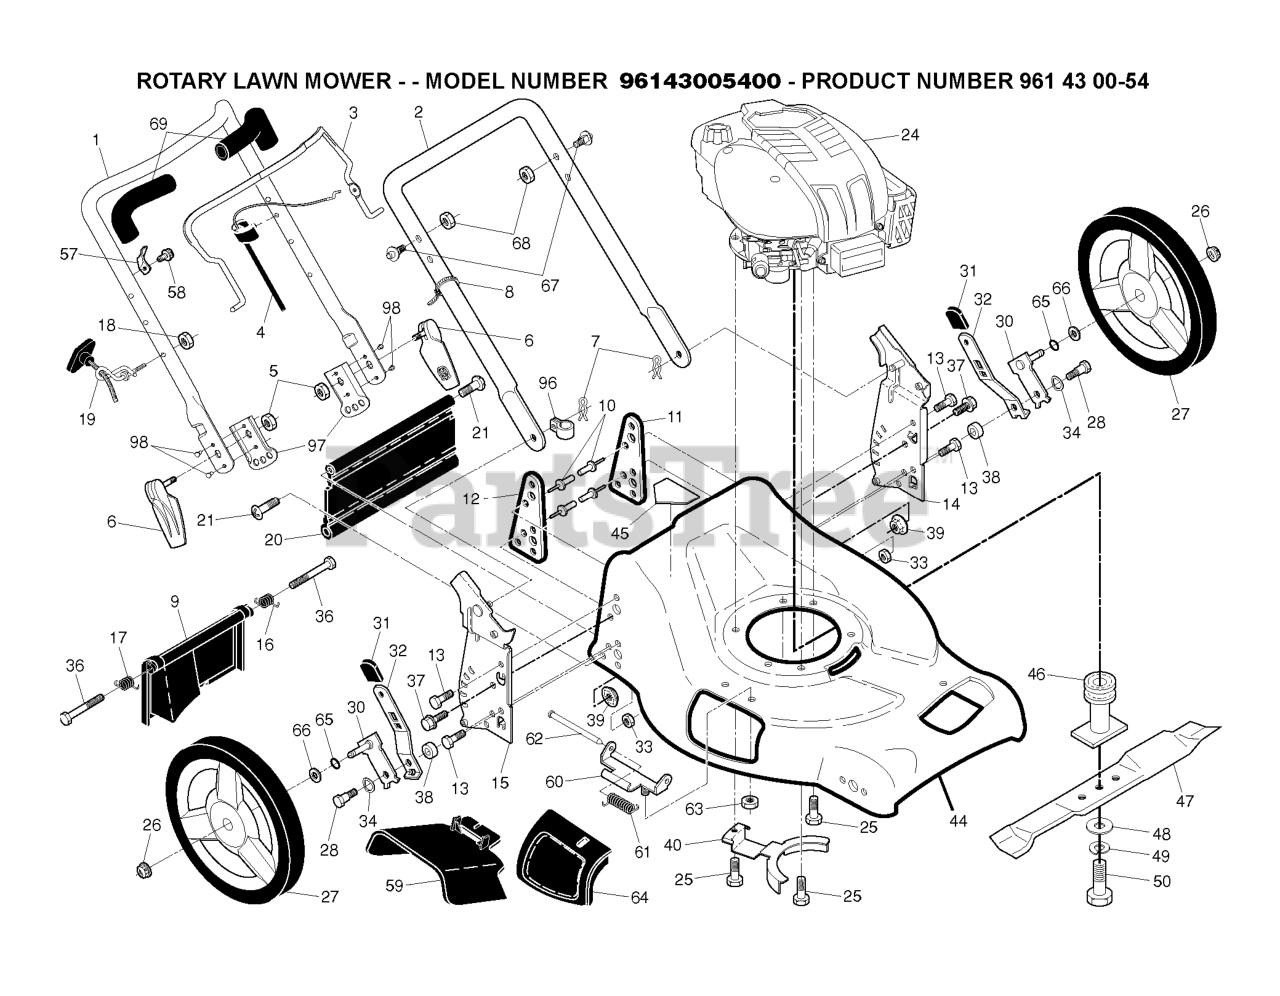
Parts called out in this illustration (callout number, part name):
1	HANDLE.ASM.UP.W/ADJ.BKT.21FGD
4	CABLE.ASM.ZONE.CONTROL
5	NUT.HEX.FLANGE.1/4
6	ASM.QUICK.RELEASE
7	HAIRPIN COTTER
8	TIE GUIDE
9	REAR DOOR ASSEMBLY
10	RIVET BLIND
11	SUPPORT BRACKET LH
12	BRACKET.SUPRT.RH.21.FWGD
13	SCREW 14-20 X 5/8
14	RP BRACKET.ASM.HNDL/HW.LT.21.
15	BRACKET.ASM.HNDL/HW.RT.21.PNT
16	SPRING.REAR.DOOR.EZ.21.LT
17	SPRING.REAR.DOOR.EZ.21.RT
18	NUT
19	RB GUIDE.ROPE.STD.BLK.ZIN WSL
20	SKIRT.REAR.21 FWGD.BLACK
21	HINGE SCREW
25	BOLT 3/8-16X1-1/8
26	NUT.HEX.FLANGE.3/8-16.LOCKNUT
27	WHEEL ASSY
28	SHOULDER BOLT 5/16-18
30	ARM.ASM.AXLE.REAR.5/9.POS.BZP
31	SELECTOR KNOB
32	SELECTOR SPRING
33	NUT.71038.31-18.HEX.NYLOCK
34	WASHER.CURVED.CYLINDRICAL
37	BOLT.FIN.HEX.5/16-18X3/4
38	SPACER.HEIGHT.ADJUSTER
39	NUT.FLANGE.5/16
40	BRACKET.KEEPER.BELT
44	HOUSING.21.FWD.ORANGE.WALK
45	DANGER DECAL
46	Blade Adapter / Pulley
47	BLADE.21.PUSH/RWGD/FWGD
48	WASHER,HARDEN
49	LOCKWASHER
50	SCREW, HEX HD 3/8-24 X 1-3/8
57	BRACKET
59	DEFLECTOR.CLIPPIN.21.FGD
60	BRACKET.ASM.HINGE.21.FWGD.
61	SPRING.TORSION
62	ROD.HINGE.21
63	LOCKNUT.NYLOC.1/4-20
64	DOOR.MULCH.21.REAR.FWGD
65	O-RING..070X.487.NEOPRENE
66	WASHER.FLAT.1/2
67	STUD.QUICK.ADJUST
68	NUT.LOCK.5/16-18
69	GRIP.HANDLE.FOAM.WIDE.(1 SIDE)
96	CLIP.CABLE.BLK
97	BRACKET.ADJ.3POS.GREY
